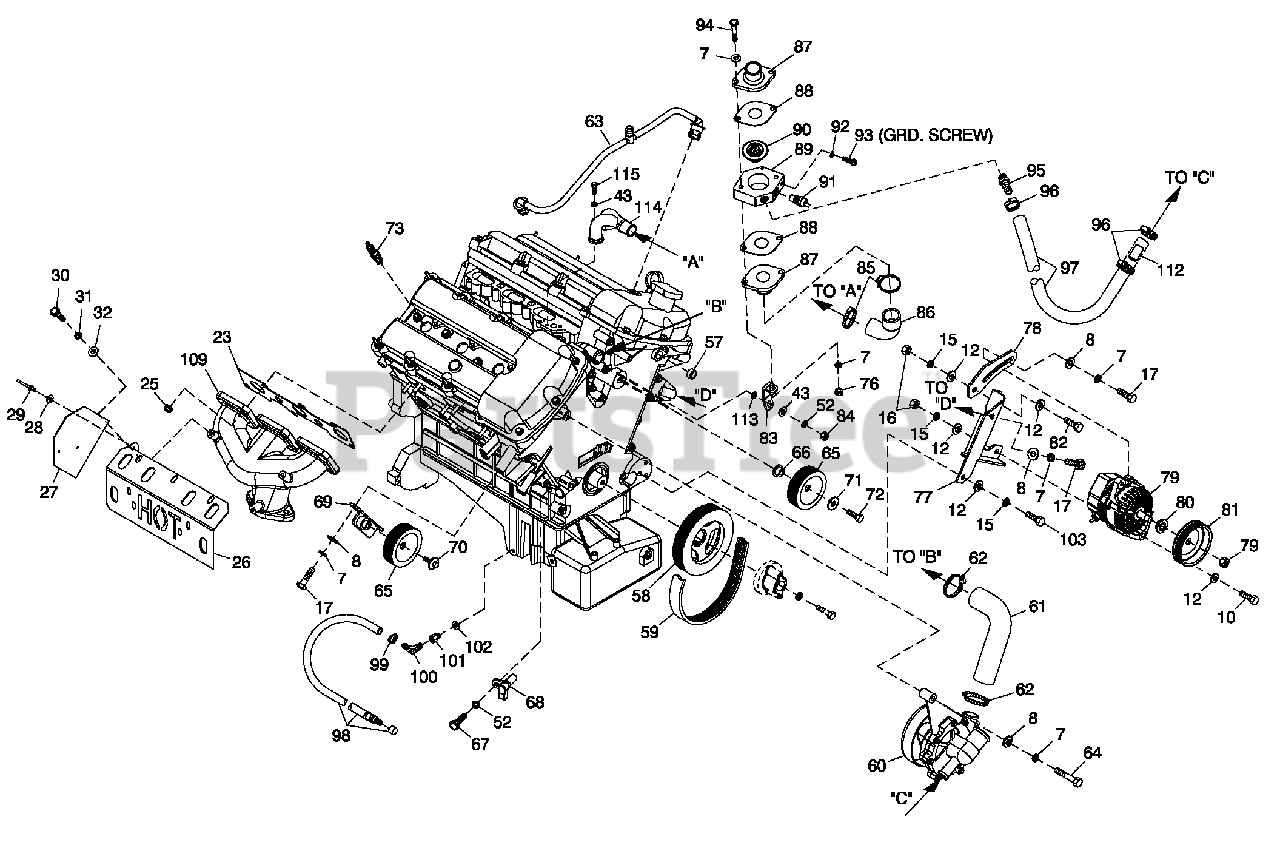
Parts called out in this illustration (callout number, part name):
1	ENGINE 3.0L G3 LS (RWD) MAKE
2	ADAPTER ENGINE
3	FLEX PLATE 2 POLE
4	SPACER FLEX PLATE
5	STARTER MOTOR 12V
6	SCREW SHC M8-1.25 X 30 G12.9
7	WASHER LOCK M8-5/16
8	WASHER FLAT 5/16-M8 ZINC
9	WASHER SHAKEPROOF EXT 7/16 STL
10	SCREW HHC M10-1.5 X 45 G8.8 FT
11	SCREW HHC M10-1.5X60G8.8
12	WASHER FLAT 3/8-M10 ZINC
13	SCREW HHC M10-1.0X25G10.9
14	WASHER FLAT .45X1.00
15	WASHER LOCK M10
16	NUT HEX M10-1.5 G8YEL CHR
17	SCREW HHC M8-1.25X 25 G8.8
18	ADAPTER OIL FILTER 3.0L
19	OIL FILTER
20	BSHG RDCR HEX 3/8 TO 1/8 GALV
21	SWITCH OIL PRESSURE 10 PSI 2 POL
22	DIP STICK OIL 3.0L
23	GASKET EXHAUST
24	MANIFOLD EXHAUST LH
25	NUT HEX FLWHIZ M8-1.25
26	HEAT SHIELD EXHAUST 3.0L
27	REFLECTIVE HEAT SHIELD 3.0L
28	WASHER FLAT #6 ZINC
29	RIVET POP.125X.400 AL
30	SCREW HHC 1/4-20 X 1/2 SS
31	WASHER LOCK 1/4-M6SS
32	WASHER FLAT 1/4 SS
33	OIL FILLER CAP 3.0L
34	DECAL REFER TO OWNERS MANUAL
35	BRACKET COIL
36	WASHER LOCK M5
37	NUT HEX M5-0.8 G8 CLEAR ZINC
38	SCREW HHC M5-0.8X 25 G8.8
39	MANIFOLD INTAKE LOWER REWORK
40	PLUG EXPANSION 14 OD
41	GASKET INTAKE MANIFOLD LWR G3
42	SCREW HHC M6-1.0X 80 C8.8
43	WASHER FLAT 1/4-M6 ZINC
44	SCREW HHC M6-1.0X120C8.8
47	MANIFOLD INTAKE UPPER
48	ASSEMBLY HOSE PCV VALVE
49	GASKET INTAKE ADAPTER
50	GASKET IDLE AIR CONTRL ACT CVR
51	COVER IAC ACTUATOR
52	WASHER LOCK M6-1/4
53	SCREW HHC M6-1.0X 16 G8.8
54	EGR GASKET
55	COVEREGR
56	SCREW HHC M8-1.25X20G8.8
57	PLUG, EXPANSION 16MM
58	REWORK HARMONIC BAL 3.0L RWD
59	BELT SERPENTINE 71.04"
60	WATER PUMP 3.0L
61	HOSE WATER PUMP 3.0L
62	CLAMP HOSE #24 B1.06-2.00
63	REWORK BREATHER TUBE 3.0L G3 LS
64	SCREW HHC M8-1.25X65G8.8
65	PULLEY GROOVED ENGINE IDLER
66	SPACER IDLER PULLEY 3.0L
67	SCREW HHC M6-1.0X20G8.8
68	SENSOR CRANKSHAFT SPEED 3.0L
69	WELDMENT IDLER BRACKET 3.0L
70	BOLT HEX FL HD M8-1.25X 28
71	SPACER .34 X 1.00 X.11 STL/ZC
72	SCREW HHC M8-1.25X35G8.8
73	SPARK PLUG (PLATINUM) .044 GAP
74	WASHER SHAKEPROOF EXT 5/16 STL
76	NUT HEX M8-1.25 G8 CLEAR ZINC
77	BRACKET DC ALTERNATOR LOWER
78	BRACKET TENSIONER
79	ALTERNATOR DC W/OUT PULLEY
80	SPACER DC ALTERNATOR PULLEY
81	PULLEY 132 OD DC ALTERNATOR
82	SCREW HHC M10-1.5X25G8.8
83	BRACKET THERMOSTAT 3.0L
84	NUT HEX M6X1.0G8YELCHR
85	CLAMP HOSE #28 1.32-2.25
86	HOSE UPPR RAD REAR
87	ADAPTER THERMOSTAT
88	GASKET THERMOSTAT
89	MACHINING,THERMOSTAT ADPTR
90	THERMOSTAT 195 DEG
91	SWITCH HI-TEMP 245D X 3/8 NPT
92	WASHER LOCK M5
93	SCREW HHTT M5-0.8X 10 BP
94	SCREW HHC M8-1.25X80G8.8
95	BARBED STR 1/2NPTX 3/4
96	CLAMP HOSE #10 .56-1.06
97	HOSE COOL 3/4 ID 20R3 (22" LG)
98	HOSE OIL DRAIN ASSY 21"
99	CLAMP HOSE .38-.87
100	BARBED EL 90 3/8 NPT X 3/8
101	ADAPTER M12-1.75X 3/8 NPT
102	WASHER NYLON .50 X .87 X .06
103	SCREW HHC M10-1.5X35G8.8
104	RETAINER SPARK PLUG WIRE
105	RESTRICTORPCV
106	SPARK PLUG WIRE SET
107	COIL IGNITION
108	PLUG STD PIPE 3/8 COUNTERSUNK
109	MANIFOLD EXHAUST RH
110	SCREW HHC M6-1.0 X 50 G8.8 (INCL. WITH I/N 47)
111	GASKET INTAKE MANIFOLD UP G3
112	RESTRICTOR COOLANT BYPASS
113	WASHER SHAKEPROOF EXT 1/4 STL
114	COOLANT X-OVER CASTING
115	SCREW HHC M6-1.0X30C8.8
